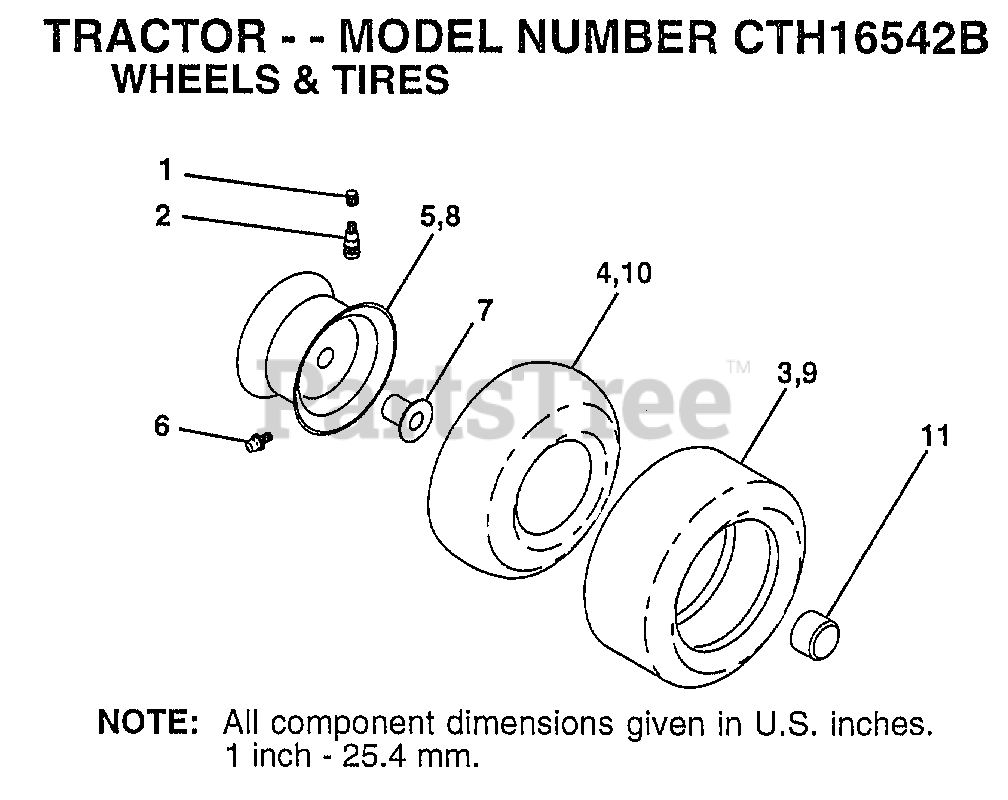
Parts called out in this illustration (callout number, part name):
1	VALVE CAP
2	VALVE STEM LT
4	TUBE.5.3/4.5/6
5	RIM.FRONT.6.YELLO
6	FITTING LT
7	"FLANGE, BEARING"
10	TUBE.18X9.5-8
11	HUB CAP
